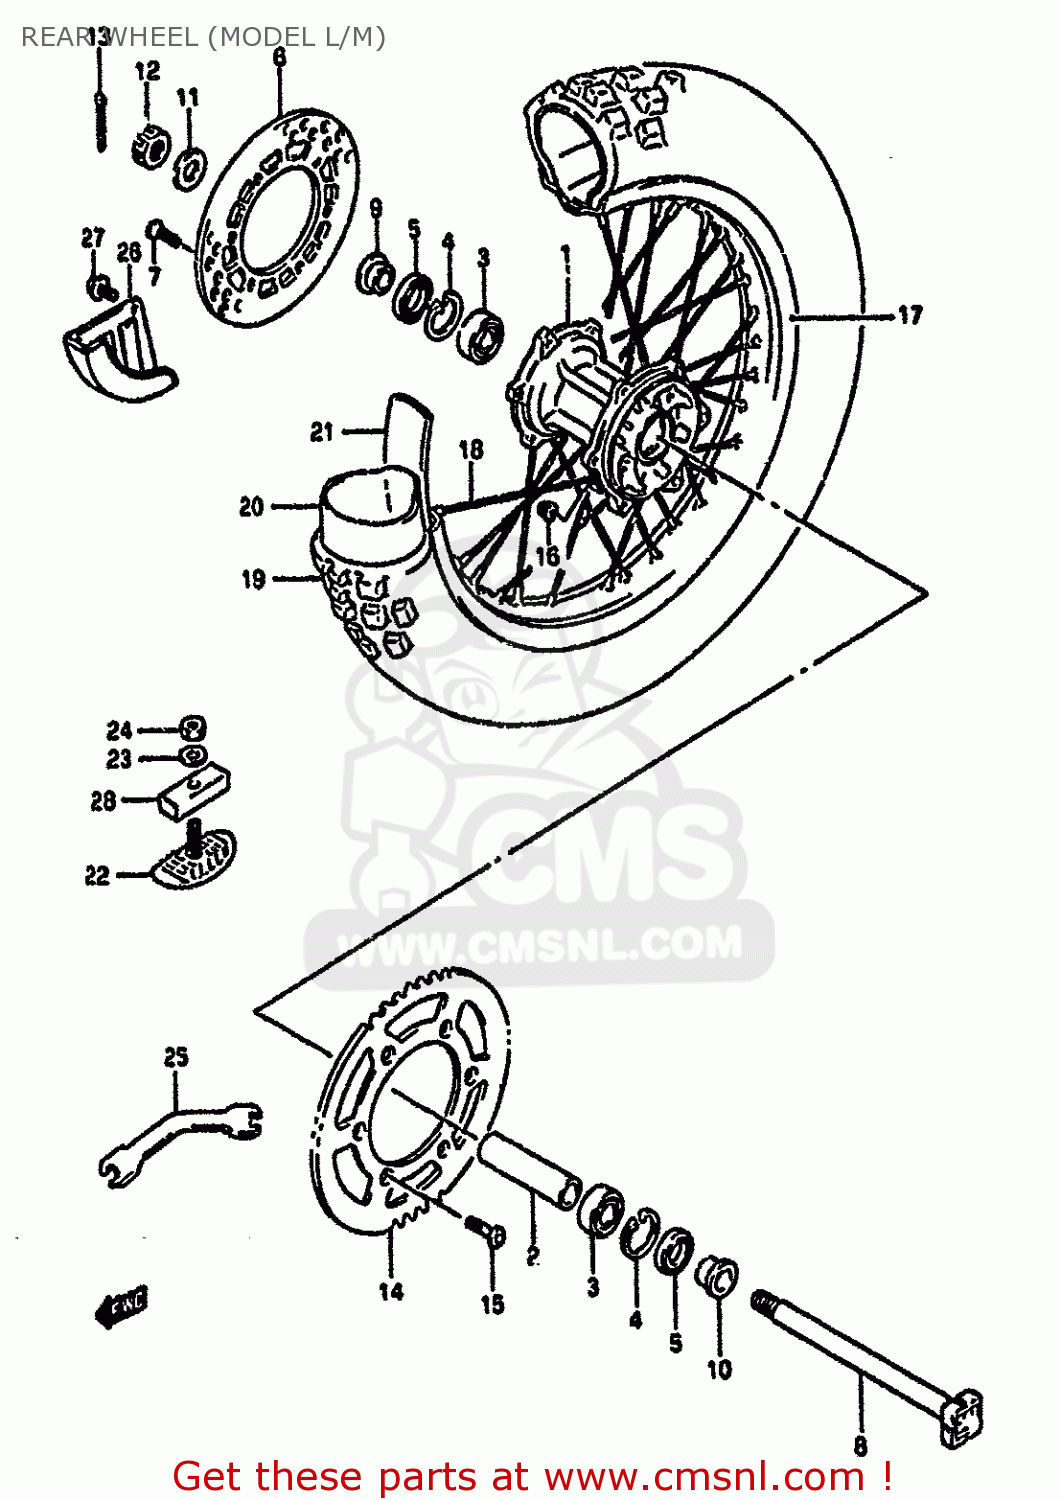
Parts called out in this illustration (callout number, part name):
1	HUB,RR
2	SPACER,RR HUB BEARING
3	BEARING WHEEL REAR(20X47X14)
4	CIRCLIP
5	SEAL,OIL(26X47X5)
6	DISC,REAR BRAKE
7	SCREW
8	AXLE,RR
9	SPACER,RR AXLE,R
10	SPACER,RR AXLE,L
11	WASHER (19X32X3.2)
12	NUT 18MM
13	PIN,COTTER
14	SPROCKET,REAR
15	BOLT(8X30.5)
16	NUT
17	RIM,REAR WHEEL (1.85X19)(A
18	SPOKE SET,REAR WHEEL
19	TIRE,REAR (100/90-19) DUNLOP
20	TUBE ASSEMBLY,WHEEL,INNER
21	PROTECTOR,WHL INR TUBE
22	STOPPER,BEAD
23	WASHER
24	NUT
25	SPANNER,OPEN
26	COVER,REAR DISC
27	BOLT
28	CUSHION,BEAD STOPPER
